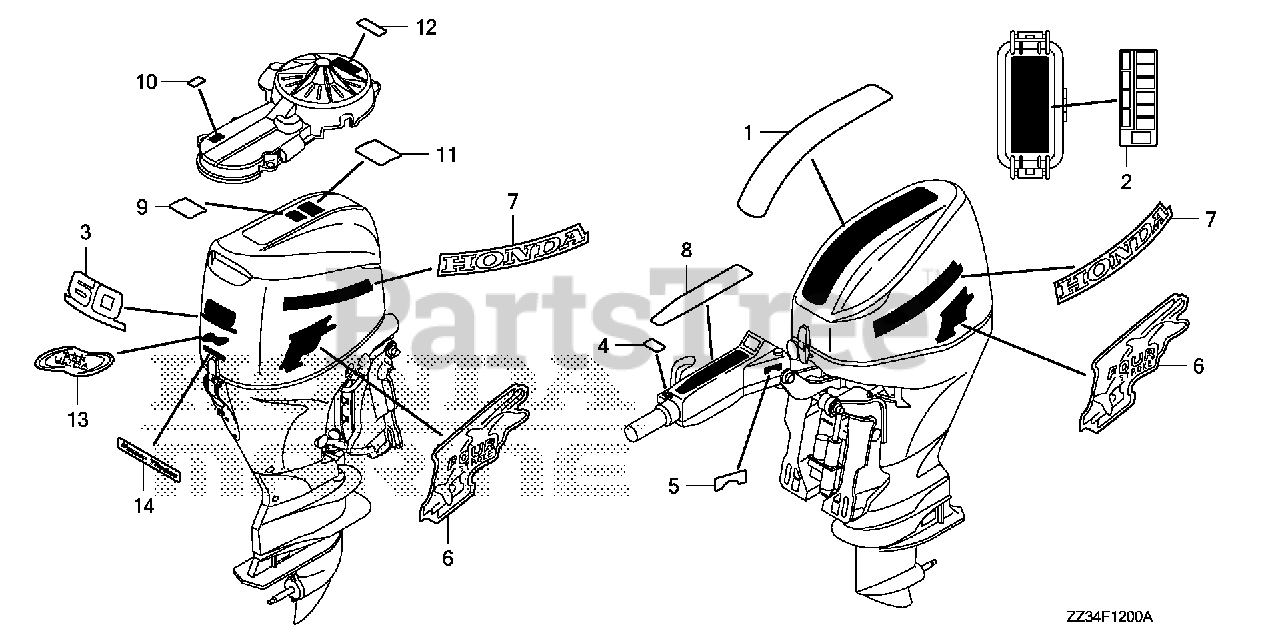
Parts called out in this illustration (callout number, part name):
1	MARK, TOP EMBLEM (60)
2	LABEL, FUSE
3	MARK, RR. (60)
6	MARK, SIDE
7	MARK, SIDE STRIPE
10	LABEL, OIL CAUTION
11	LABEL, WARNING OPERATOR (ENGLISH)
12	MARK, EMERGENCY START (ENGLISH)
